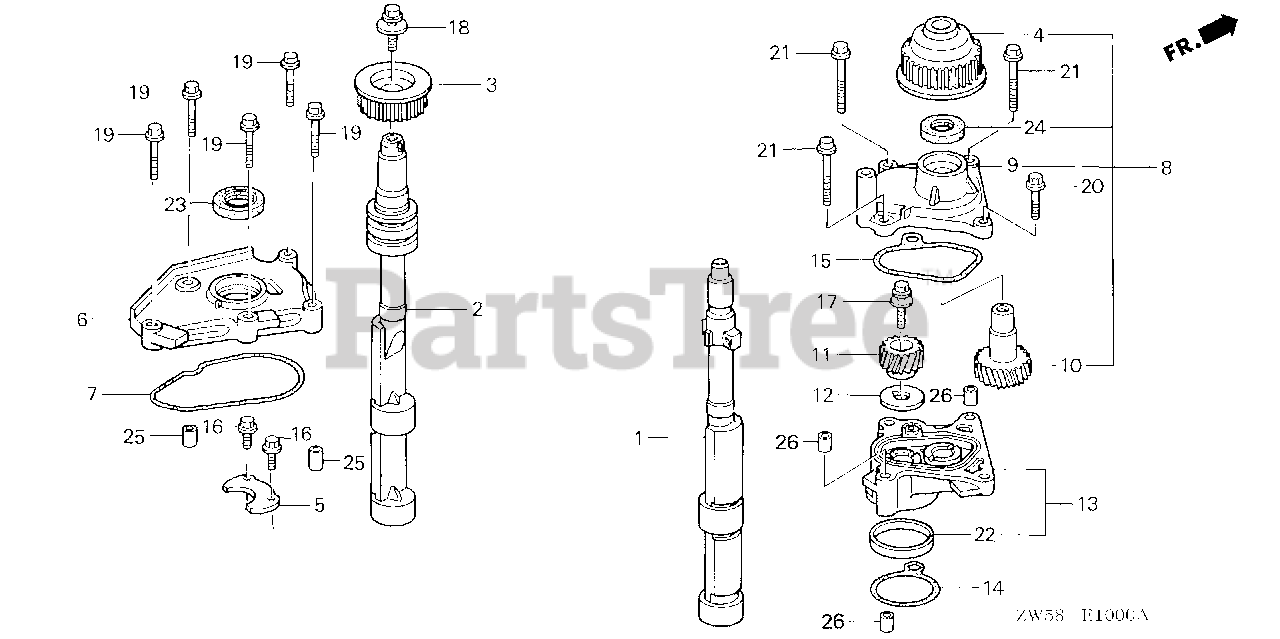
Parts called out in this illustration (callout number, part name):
1	SHAFT, RR. BALANCER
2	SHAFT, FR. BALANCER
3	PULLEY, BALANCER BELT DRIVEN (FR)
4	PULLEY, BALANCER BELT DRIVEN (RR)
5	METAL F, THRUST BALANCER SHAFT
6	COVER, BALANCER SHAFT
7	O-RING, BALANCER COVER
8	CASE, BALANCER GEAR
9	CASE, BALANCER GEAR
10	GEAR, BALANCER DRIVE
11	GEAR, BALANCER DRIVEN
12	WASHER, THRUST
13	SPACER, GEAR CASE
14	O-RING, GEAR CASE SPACER
15	GASKET B, OIL PUMP (ARAI)
16	BOLT, FLANGE (6X18)
17	BOLT-WASHER (8X33)
18	BOLT-WASHER (8X22)
19	BOLT, FLANGE (6X35)
20	BOLT, FLANGE (8X25)
21	BOLT, FLANGE (8X65)
22	PIN, DOWEL (49X10)
23	OIL SEAL (27X41X8) (NOK)
24	OIL SEAL (18X33X6)
25	PIN, DOWEL (8X14)
26	PIN, DOWEL (10X12)
